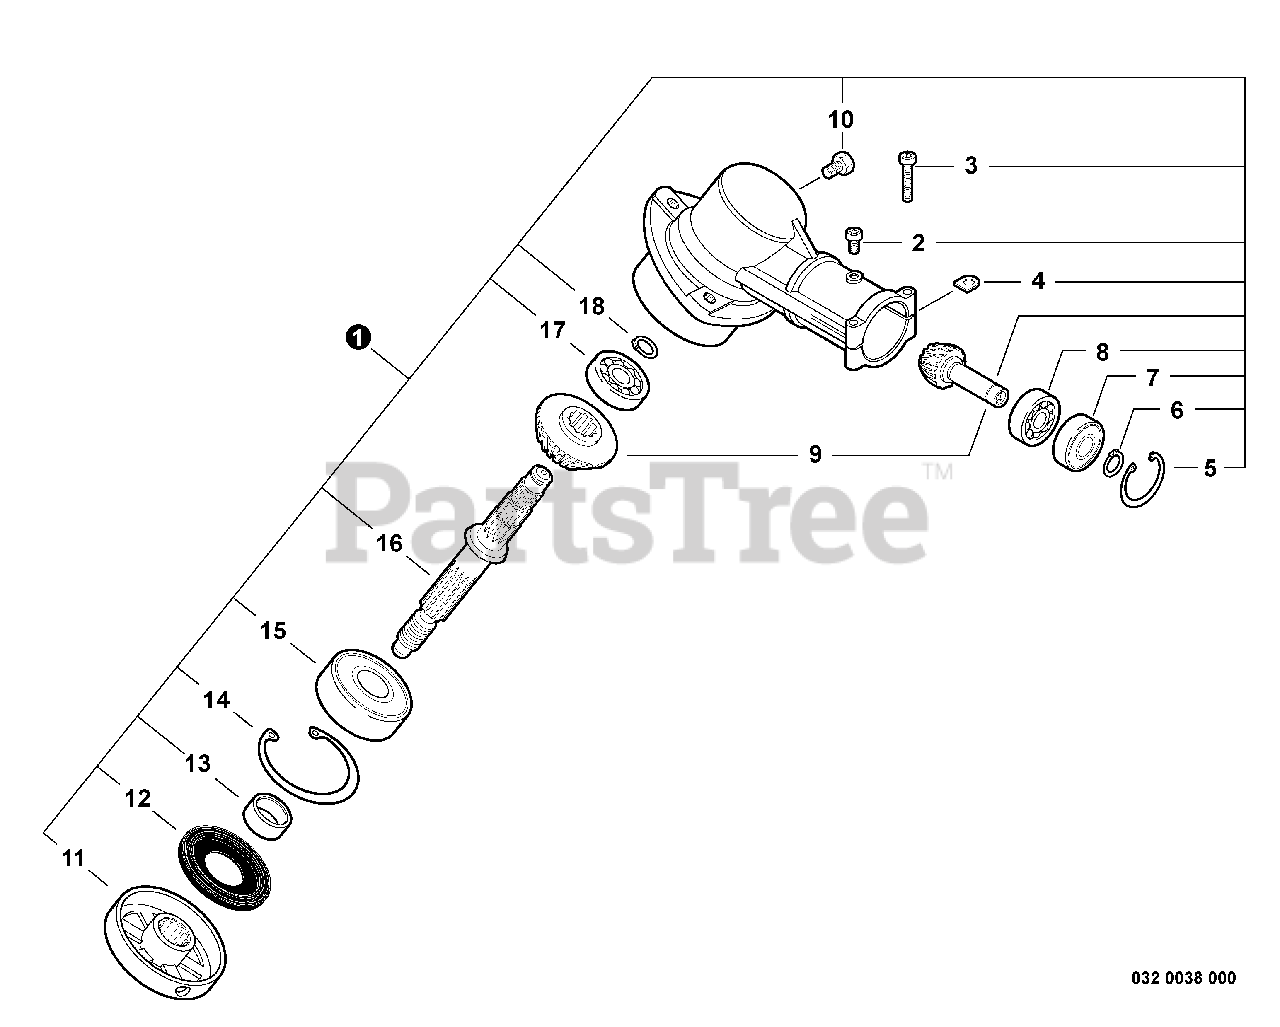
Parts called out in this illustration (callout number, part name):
1	GEAR CASE ASSY
2	BOLT, TORX 5×10
3	BOLT, TORX 5×25
5	RING, SNAP Ø22
6	RING, SNAP Ø10
7	BEARING, BALL 6900Z
8	BEARING, BALL 6900
9	GEAR SET
10	BOLT M8×8
11	PLATE, ADAPTOR - UPPER
12	SEAL, OIL 22
13	SPACER 11.8×15×9
14	RING, SNAP Ø32
15	BEARING, BALL 6201
16	SHAFT, GEAR
17	BEARING, BALL 609
18	RING, SNAP Ø12
